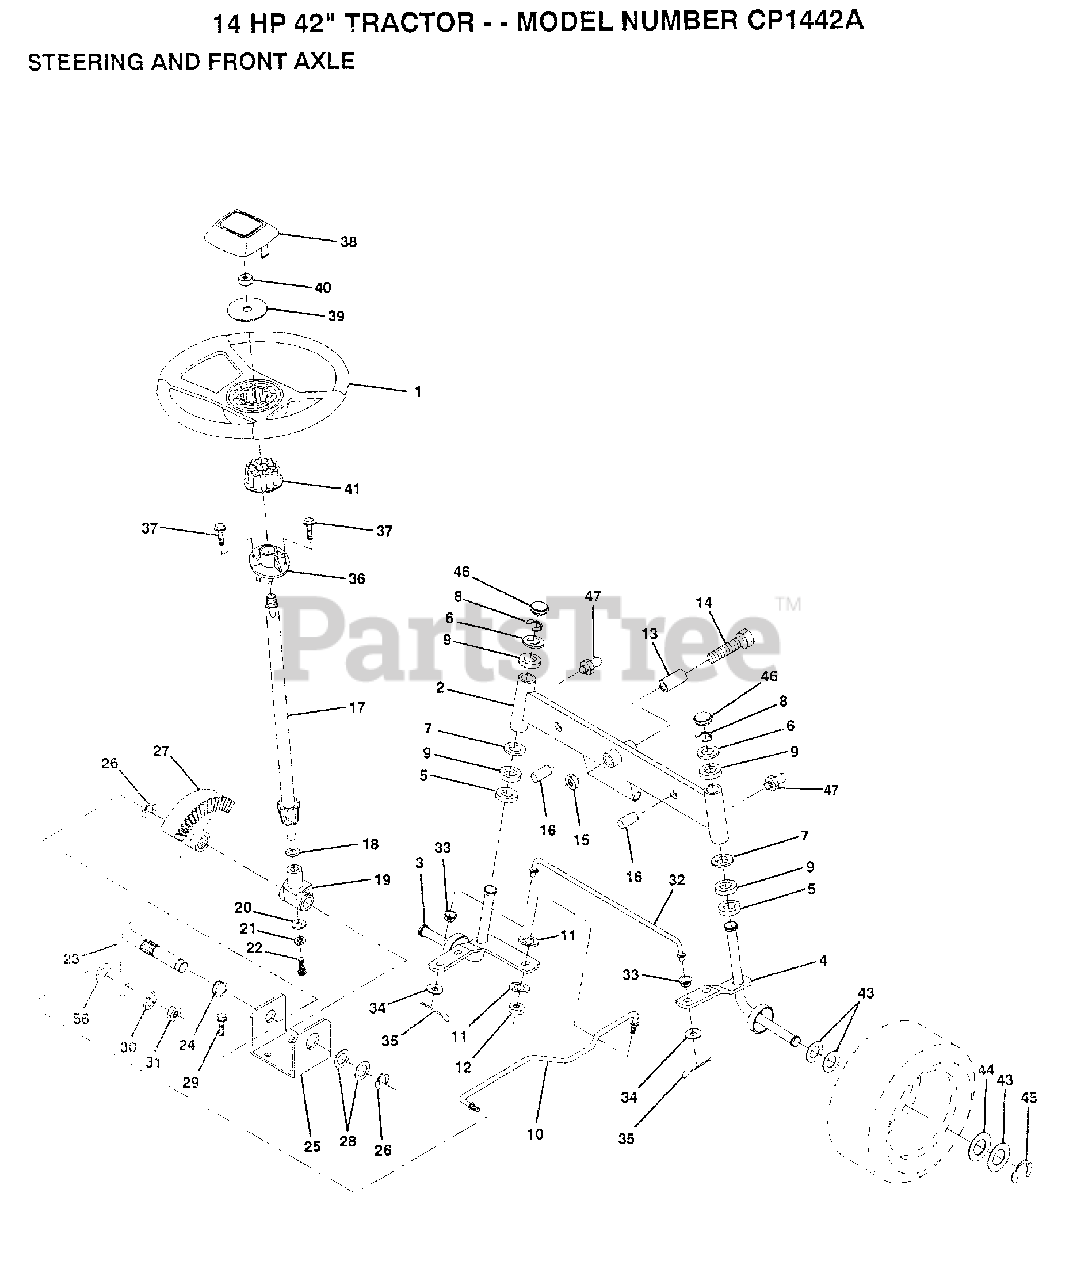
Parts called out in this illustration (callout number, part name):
3	SPINDLE LH
4	SPINDLE RH
5	WASHER .T
6	WASHER
7	WASHER
8	RING
9	COL. SRTG. BEAR.
11	LOCKWASHER
13	BEARING
14	BOLT HEX 5/8-11
15	"NUT-LOC,FLANGE LT"
16	AXLE PIN
17	STEERING SHAFT
18	THRUST WASHER
19	SUPPORT.SHAFT
21	LOCKWASHER
22	"SCREW,SPECIAL"
24	NYLINER T
25	"BRKT,STEERING"
26	RING
27	GEAR SECTOR
28	WASHER .T
29	SCREW
30	LOCKWASHER
32	TIE ROD
33	BUSHING.DRAGLINK
34	WASHER
35	COTTER PIN
38	ST WHL INSERT CAP
39	WASHER
41	ADAPTER LT
43	WASHER
44	WASHER
45	RING
46	CAP
47	ZERK M
56	WASHER
